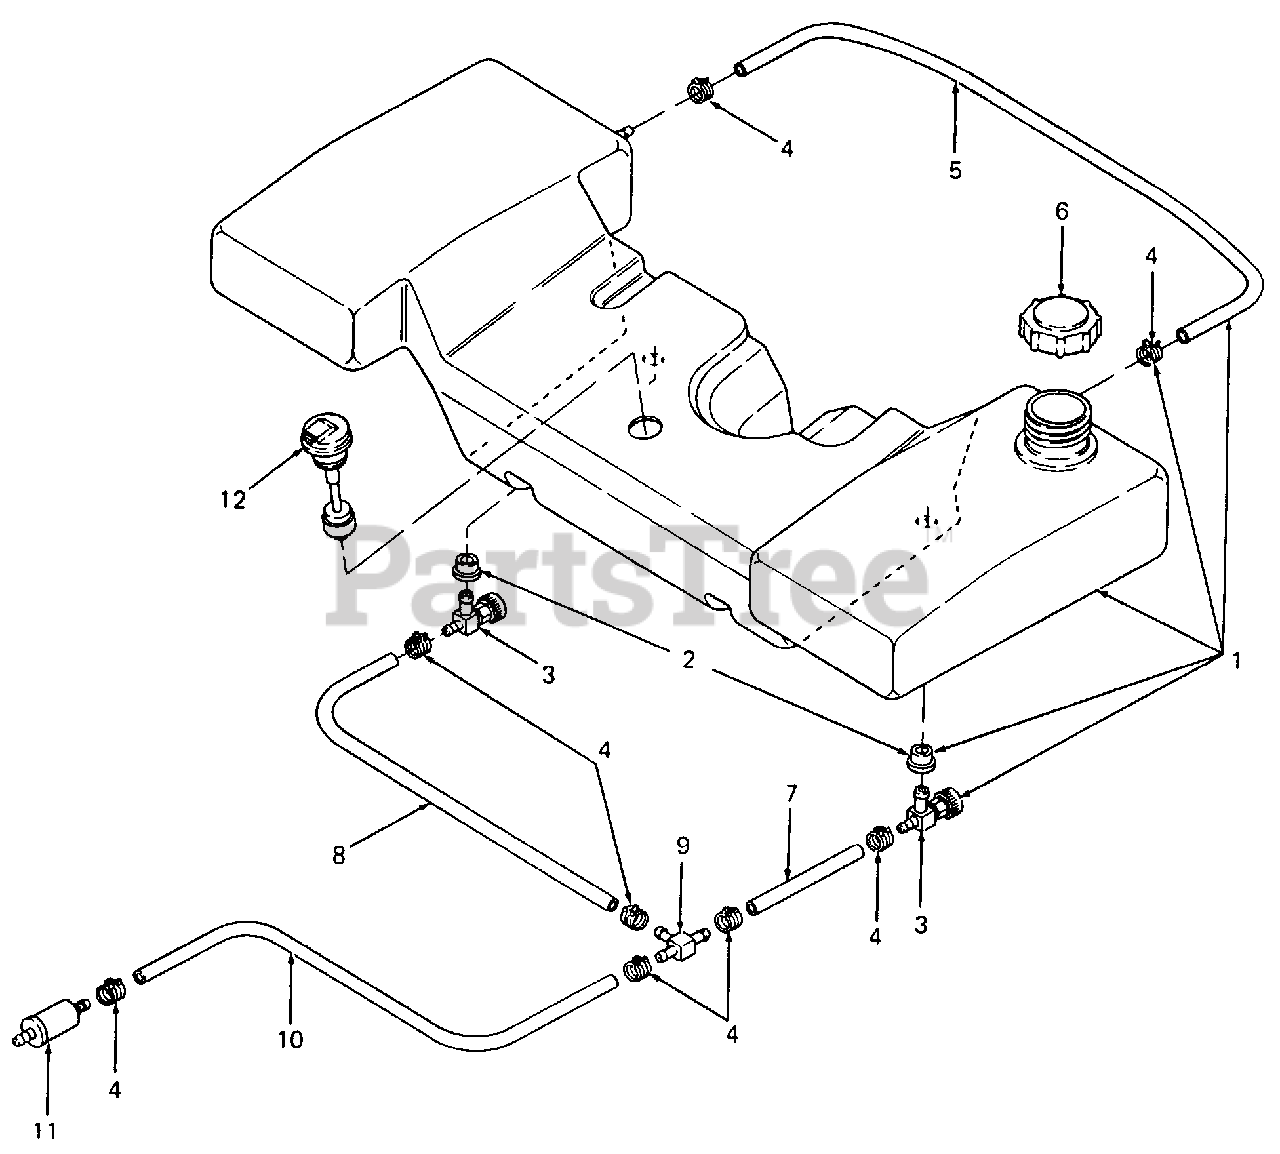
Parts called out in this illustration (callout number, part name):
1	Tank, Fuel
2	Bushing
3	Valve, Fuel Shutoff
4	Clamp, Hose
5	Line, Fuel -24" Lg
6	Cap, Fuel
7	Line, Fuel -5" Lg
8	Line, Fuel -17" Lg
9	T-Fitting
10	Line, Fuel -47" Lg
11	Filter, Fuel
12	Sensor, Low Fuel
